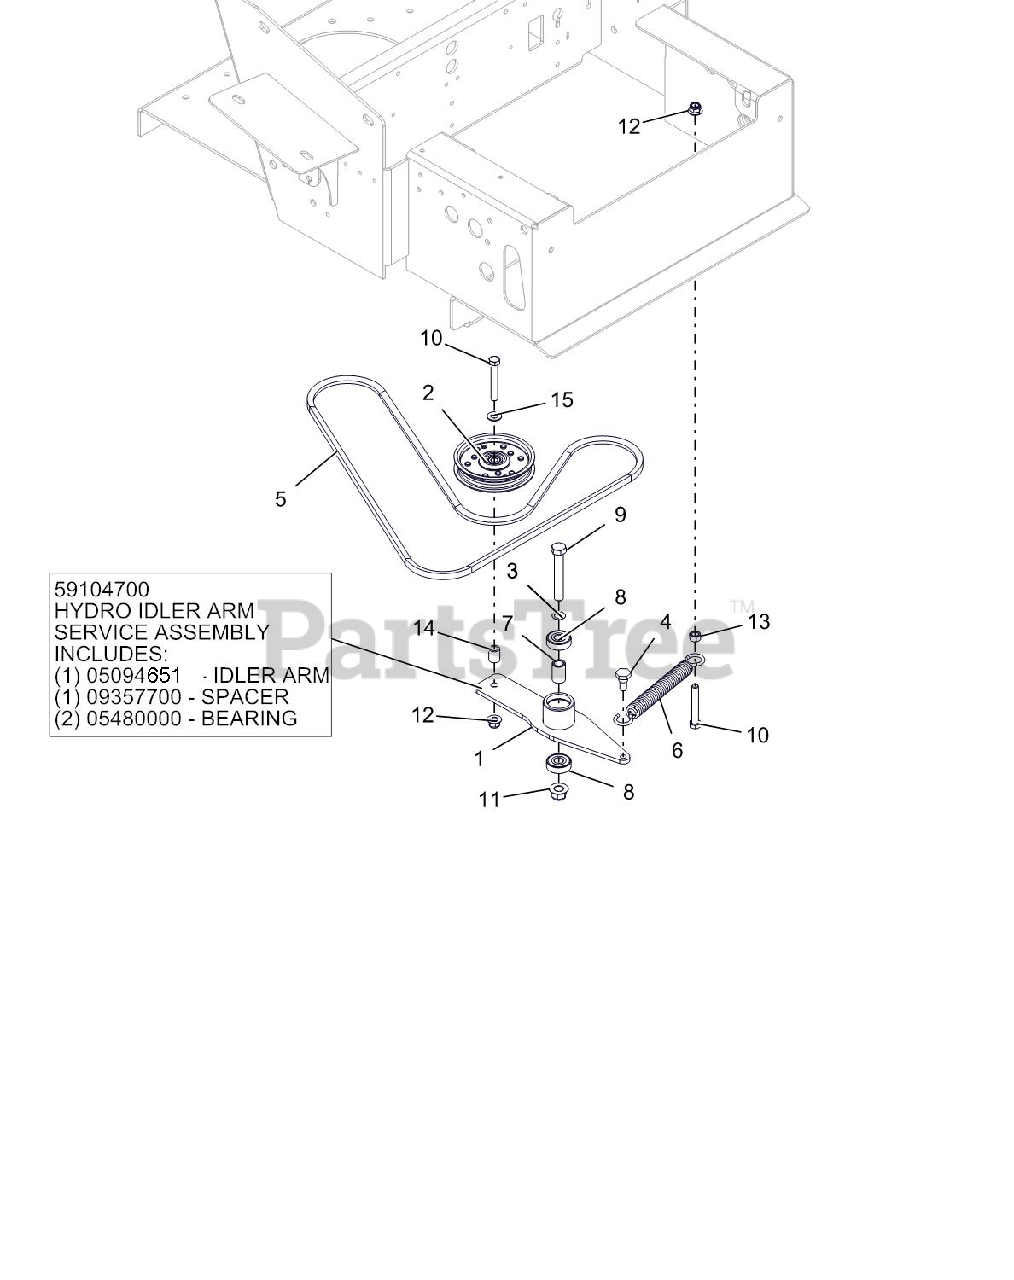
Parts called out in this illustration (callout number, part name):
1	BRG-BALL .50X1.38X.438 SEALED
1	SPACER .510 X .75 X 1.1485
1	HYDRO IDLER ARM ASSEMBLY
1	HYDRO DRIVE IDLER ARM WMT-BLK
2	ASM, 4" IDLER (.75 WIDE)
3	WASHER, .500X.750X.020 THRUST
4	BLT,SHLDR EP .38-16X.30 HEX YZ
5	V-BELT, A-COGGED
6	SPRING, EXTENSION
7	SPACER .510 X .75 X 1.1485
8	BRG-BALL .500X1.38X.437
9	@BLT-HEX .50-13X3.25 GR5 YWZC
10	@BLT-HEX .38-16X2.50 GR5 YWZC
11	@NUT-LK-NYL-FLG .50-13 YWZC
12	@NUT-LK-NYL-FLG .38-16 YWZC
13	@NUT-HEX .38-16 YWZC
14	BSHG-SLV .407X.625X.750 PL
15	@WSHR-FL-STL.406X.812X.065 YWZ
